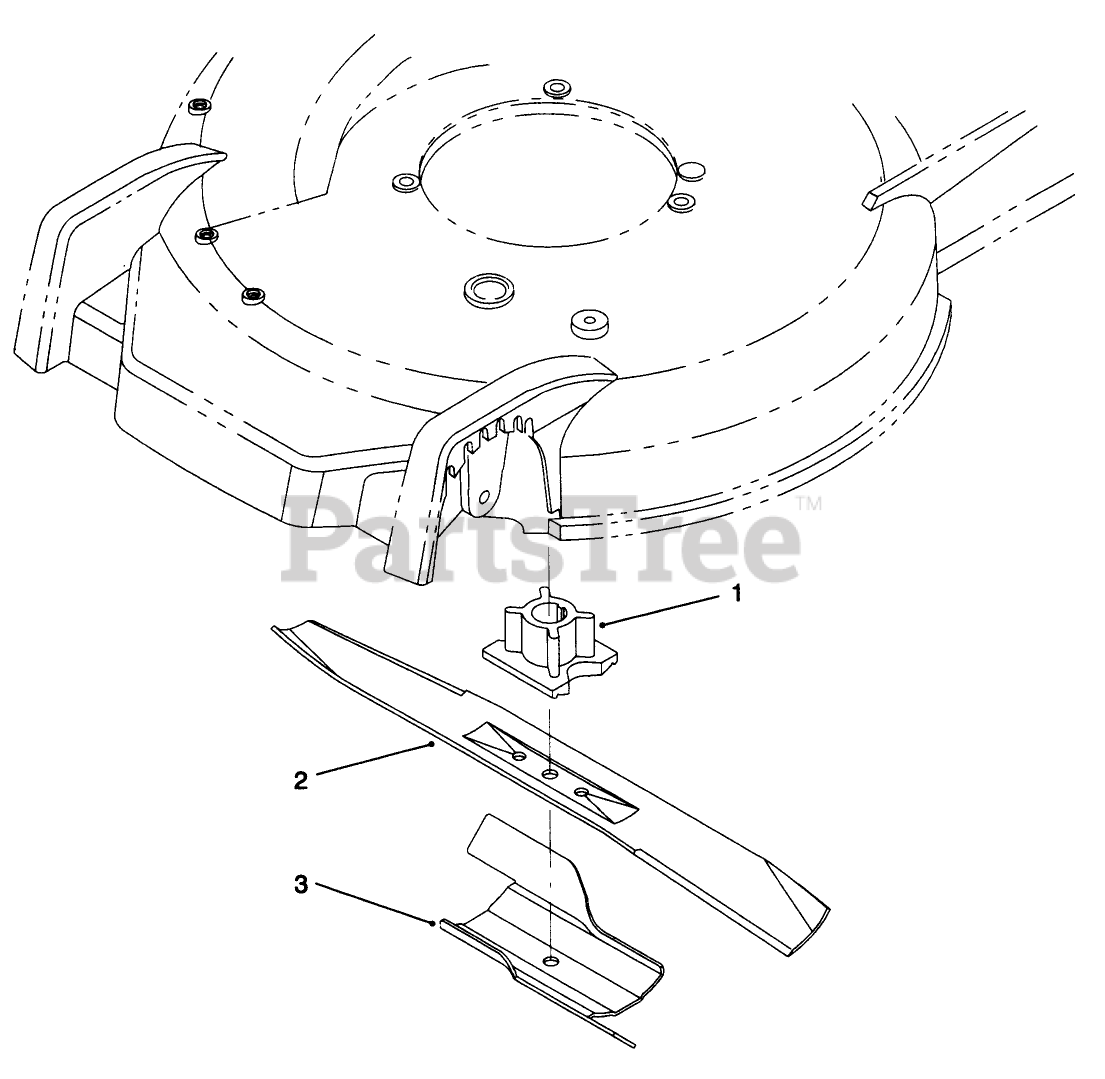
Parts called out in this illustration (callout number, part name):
1	RETAINER - BLADE
2	Blade
3	Stiffener-Blade
